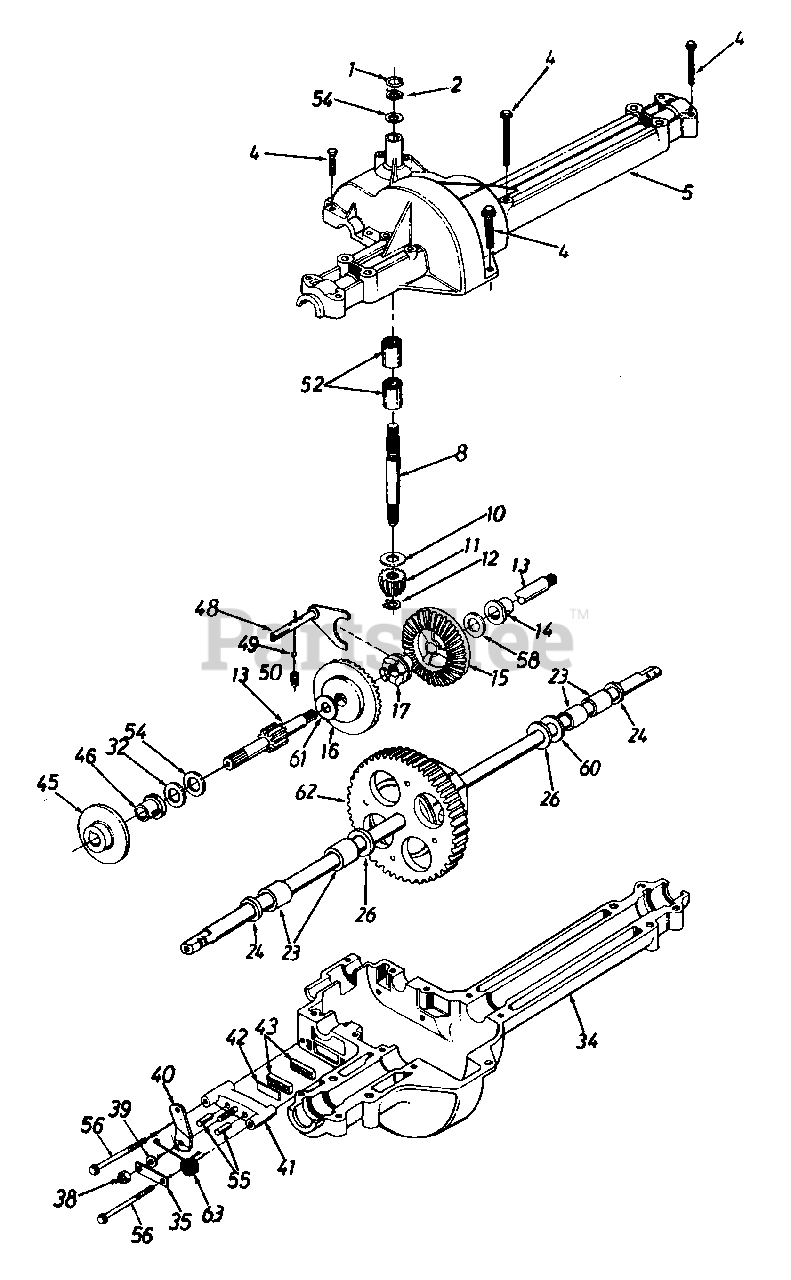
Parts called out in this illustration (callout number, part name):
1	Wire Ring
2	Retaining Ring
4	Tap Scr. 1/4-
5	Upper Housing
8	Input Shaft
10	Thrust Washer 5/8" I.D. x 1.25" Lg.
11	Pinion Input 14T
12	Retaining Ring
13	Drive Shaft L.H. Brake
14	Flange Brg. 5/8" I.D. x 3/4" Lg.
15	Bevel Gear 42T Small I.D.
16	Bevel Gear 42T Large I.D.
17	Clutch Collar
23	Sleeve Bearing 3/4" I.D. x 1.0"
24	Oil Seal 3/4" I.D.
26	Flat Washer .760" I.D. x 1.5" O.D.
32	Thrust Washer 5/8" x 1" x .025"
34	Lower Housing
35	Anti-Rotation Brkt.
38	Hex Nut 5/16-24 Thd.
39	Flat Washer .344" I.D. x .875" O.D.
40	Actuating Arm
41	Brake Yoke
42	Puck Plate
43	Brake Puck
45	Brake Disc
46	Flange Bearing 5/8" I.D. x 15/16"
48	Shift Fork Ass'y.
49	Ball Detent .250" Dia.
50	Spring Detent
52	Needle Brg. 5/8" I.D. x 1/2" Lg.
54	Flat Washer 5/8" I.D. x 1" O.D.
55	Actuating Pin 5/16" Dia.
56	Hex Wash Hd. Self-Tap Scr.
58	Flat Washer 5/8" I.D. x 1" O.D. x
60	Flat Washer .76" x 1.5" x .010"
61	Thrust Washer
62	Differential Ass'y.
63	L.H. Brake Spring
